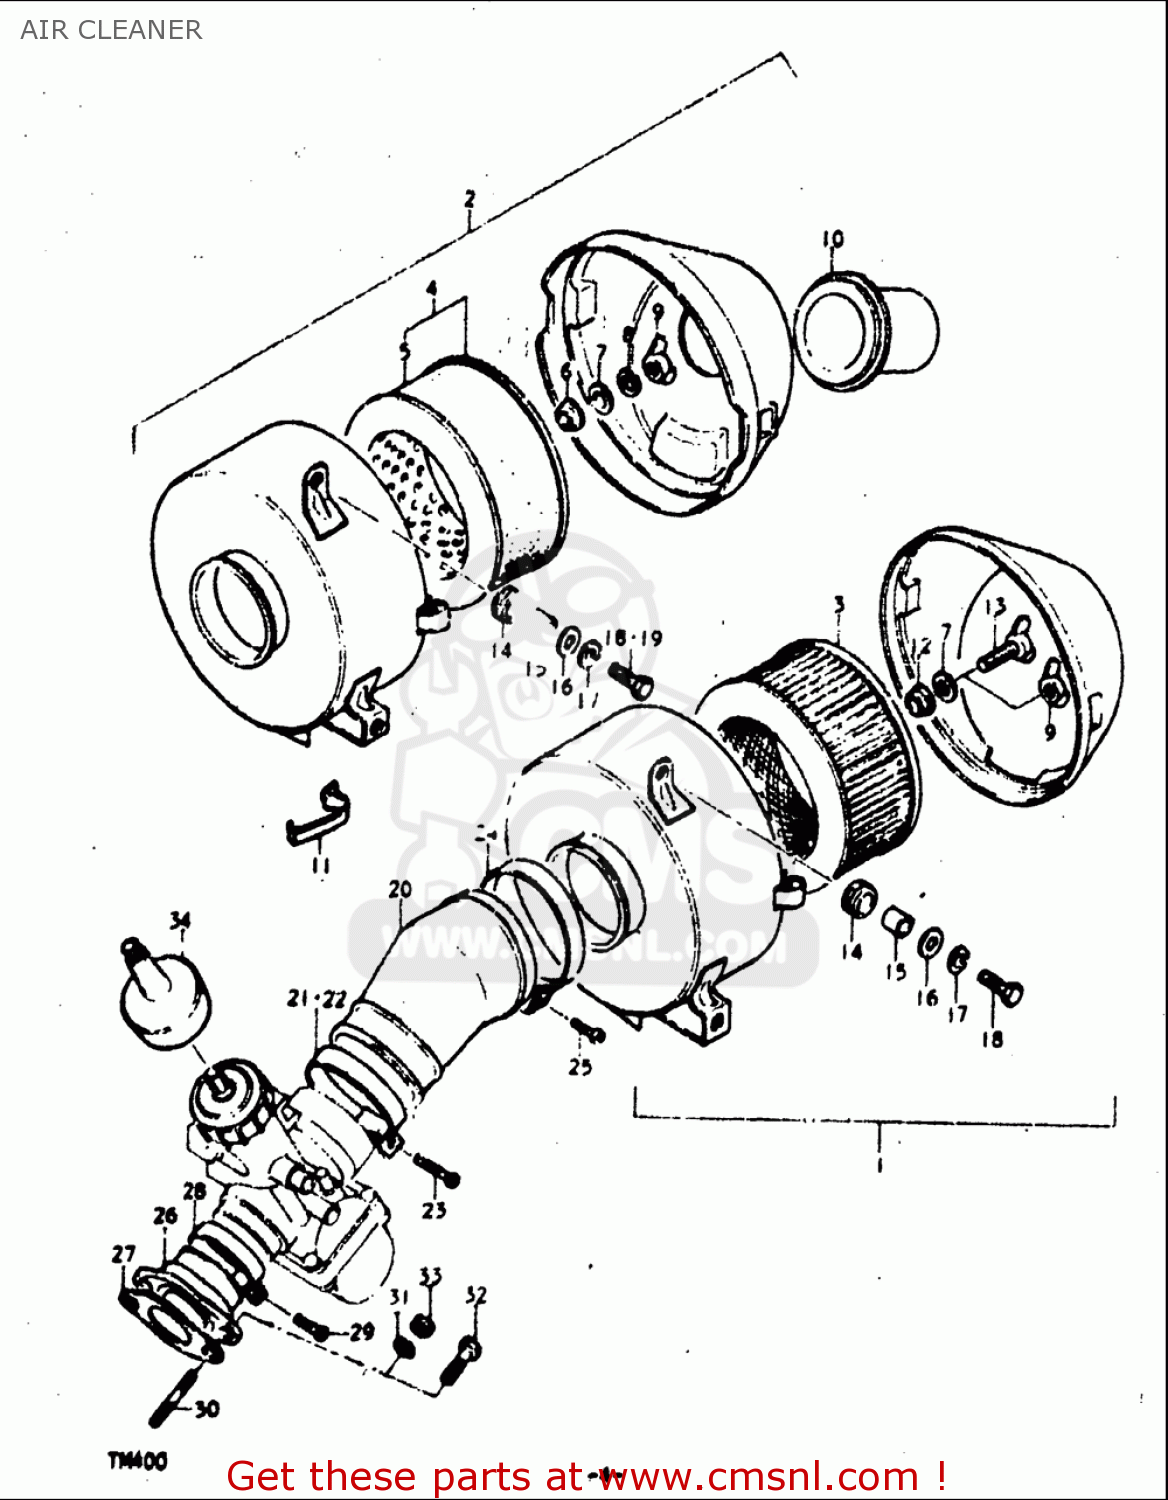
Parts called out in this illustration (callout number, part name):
7	WASHER
8	WASHER,LOCK
10	PIPE, INLET
14	CUSHION
15	SPACER,6.5X9X7
16	WASHER(6.5X20X1.2)
17	WASHER,LOCK
18	BOLT
19	BOLT
21	CLAMP
23	SCREW
24	CLAMP
25	SCREW
26	PIPE,INTAKE
27	GASKET,CARBURETOR (NAS)
28	CLAMP
29	SCREW
30	STUD BOLT
31	WASHER,LOCK
32	BOLT
33	NUT
34	CAP
